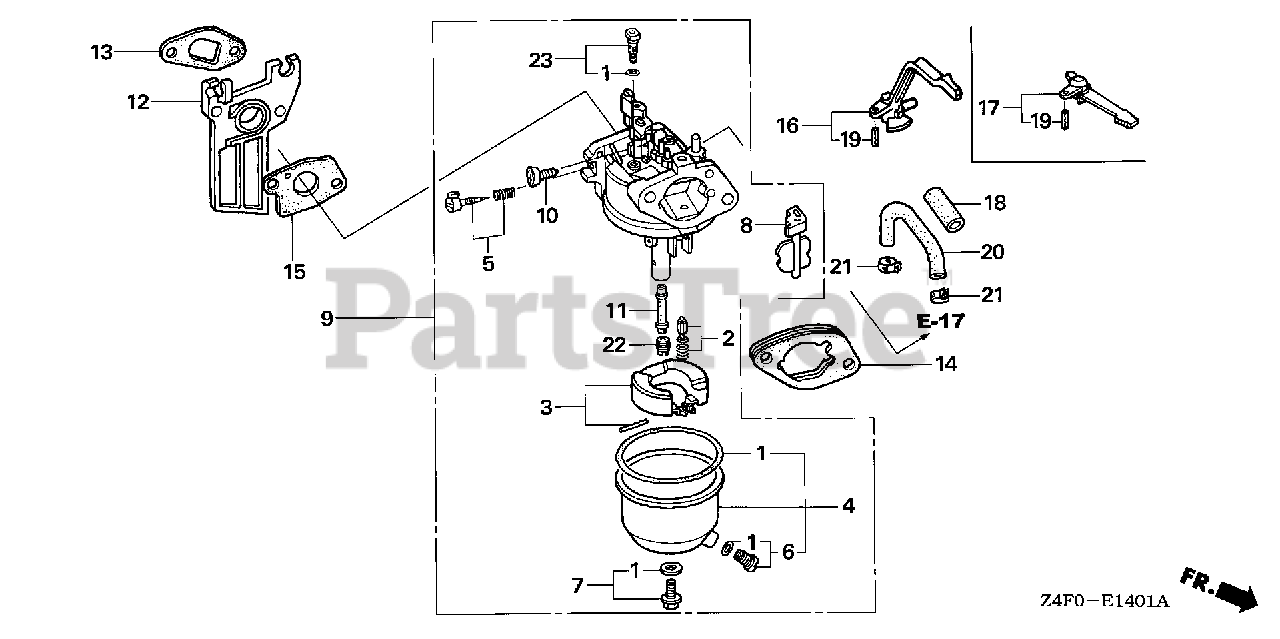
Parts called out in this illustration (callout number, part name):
1	GASKET SET
2	VALVE SET, FLOAT (SEAT NOT INCLUDED)
4	CHAMBER SET, FLOAT
5	SCREW SET, PILOT
6	SCREW SET, DRAIN
7	SCREW SET
9	CARBURETOR ASSY. (BE62C A)
10	SCREW, THROTTLE STOP
11	NOZZLE, MAIN
12	INSULATOR, CARBURETOR
13	GASKET, INSULATOR
14	SPACER, CARBURETOR
15	GASKET, CARBURETOR
17	LEVER, CHOKE (STD)
18	RUBBER, SUPPORTER (107MM)
19	PIN, SPRING (2X12)
20	TUBE, FUEL (4.5X400) (FKM)
20	BULK HOSE, FUEL (4.5X8000) (95001-450(95001-45001-60M)
21	CLAMP, TUBE (D8)
22	JET, MAIN (#58)
22	JET, MAIN (#60)
22	JET, MAIN (#62)
23	JET SET, PILOT (#35)
